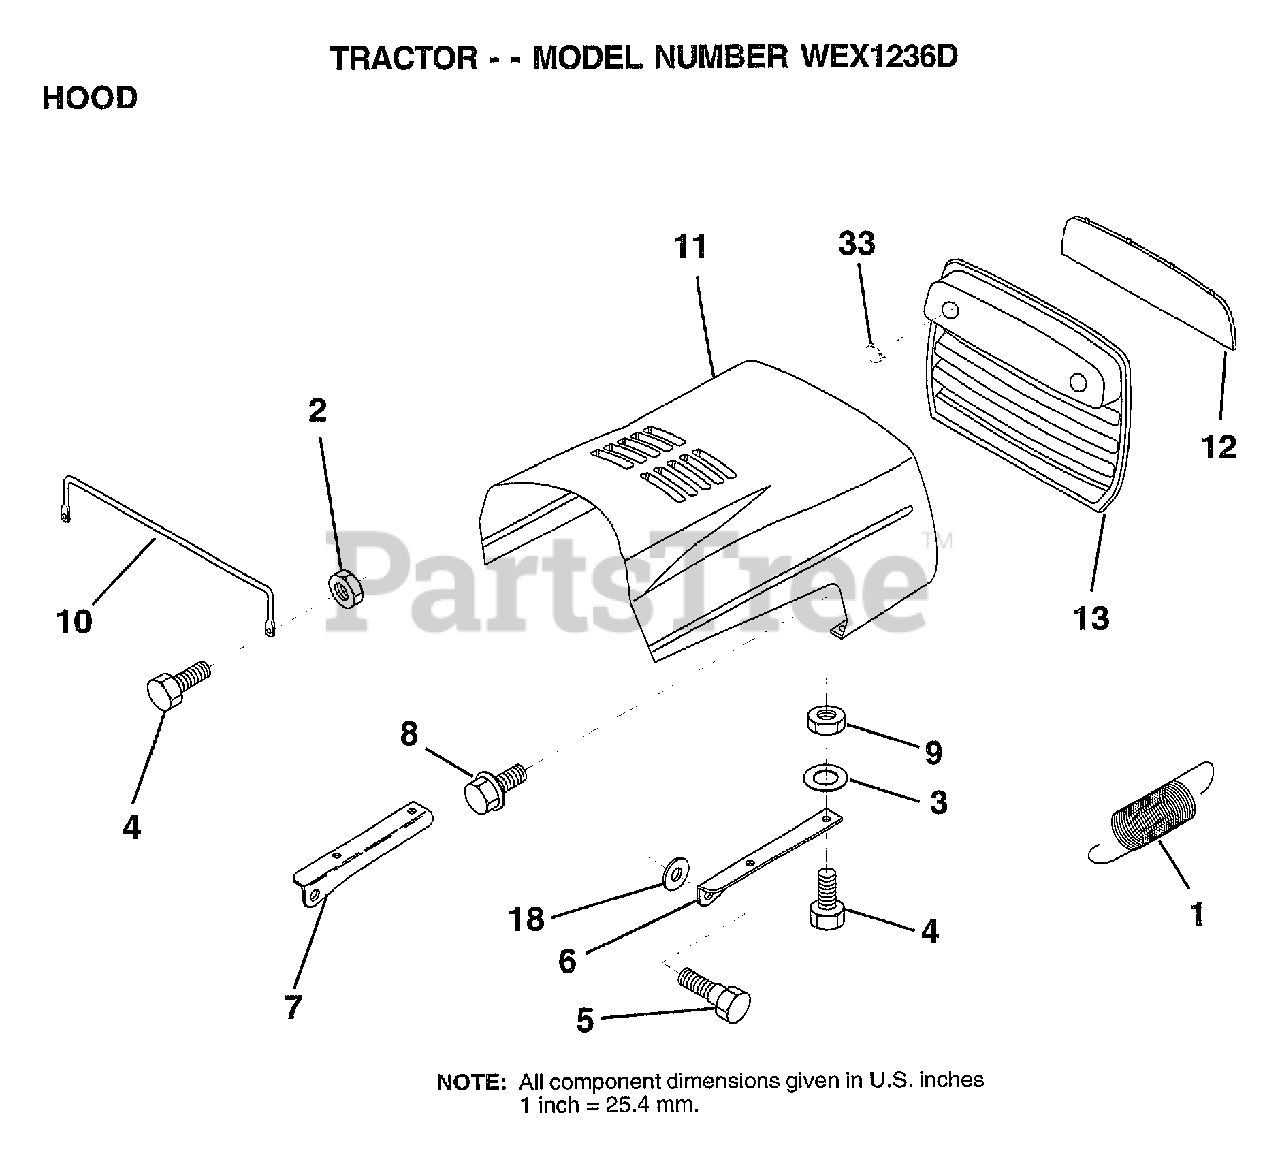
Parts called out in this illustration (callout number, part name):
1	EXT SPRING
2	NUT
3	WASHER
5	BOLT.SHLD.5/16-18
6	BRKT HOOD RH
7	BRKT HOOD LH
8	"SCREW,HWHD.HI-LO#13-16X3/4"
9	NUT
10	"BRACE,HOOD"
11	HOOD.IMPREG.MS550
12	LENS
13	GRILL
18	WASHER
